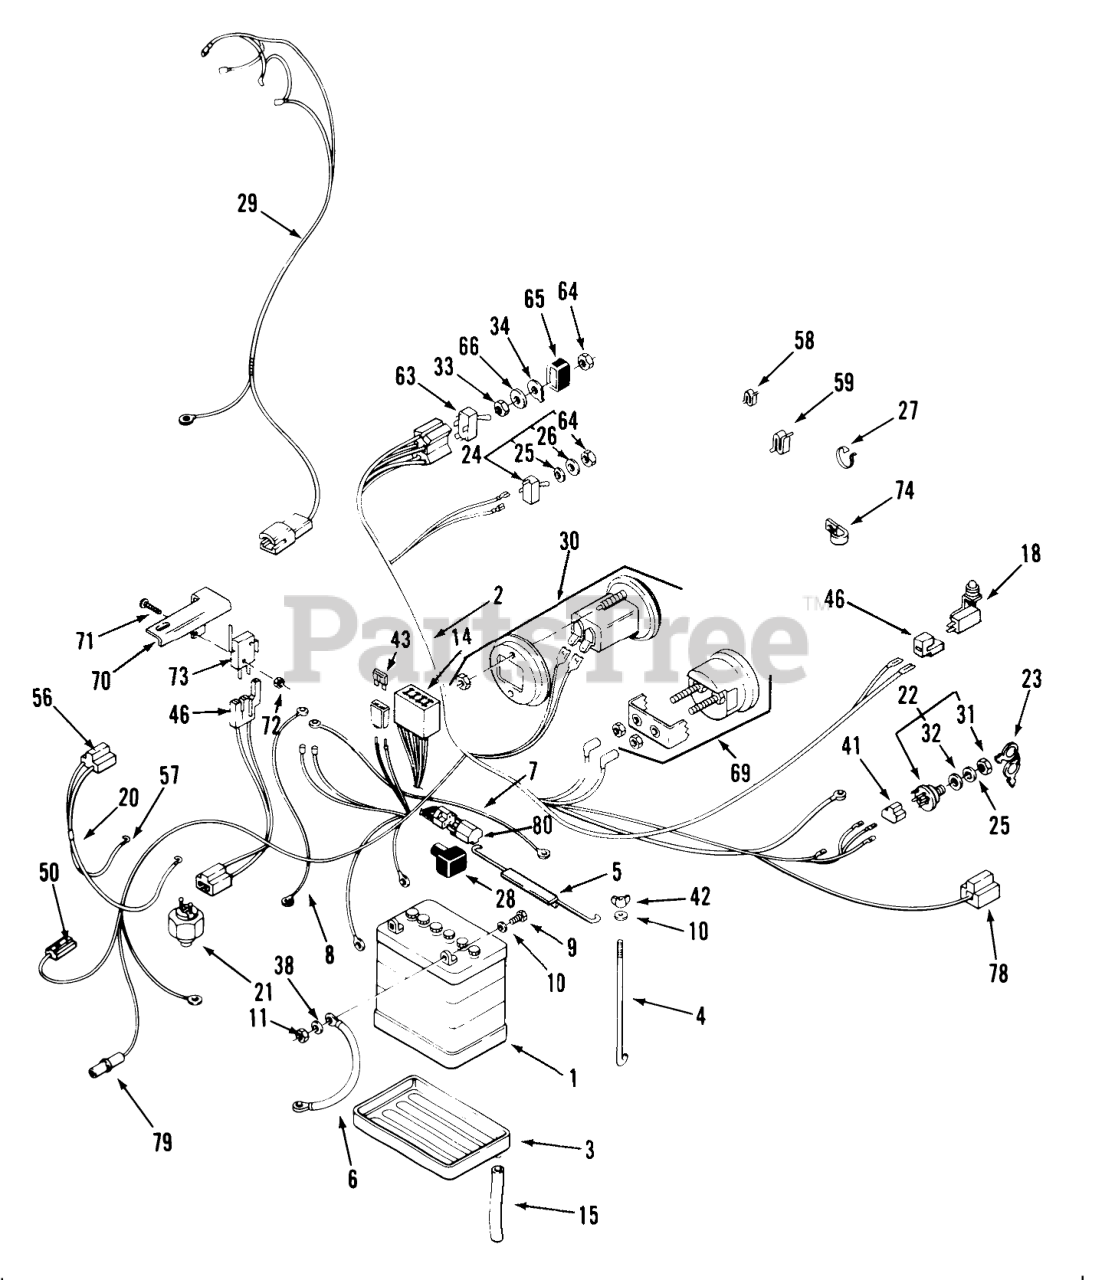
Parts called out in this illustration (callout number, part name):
1	Battery
2	MAIN-HARNESS & DIA
3	TRAY-BATTERY
5	ROD-BATTERY HOLD DWN
6	WIRE -BLACK
7	WIRE - 14" BLACK
8	ASS'Y-WIRE
9	Bolt
11	Nut
14	FUSE-HOLDER 4 WAY
15	TUBE-BATTERY DRAIN
18	Seat Switch
20	ASSY WIRING HARNESS
21	SWITCH (N.C.-TRANS)
22	Ignition Switch (Includes items 31 & 32)
23	Ignition Key
24	Light Switch (Includes items 33 & 34)
25	Washer
26	Washer
27	PLASTIC TIE
28	Boot
29	HARNESS-HEADLIGHT
30	Hourmeter (Includes 114017 Bracket, 915962 Keps Nut 2] & 5924 E.S. Nut #10-24 2])
32	LOCKWASHER
33	NUT-HEX, SPECIAL
34	TAB-WASHER
41	CONNECTOR-5 WAY-SERV
42	Nut
43	FUSE-BLADE, 15 AMP
46	CONNECTOR BODY
50	CONNECTOR BODY ELECT
56	CONNECTOR BODY B
57	TERMINAL-TAB RCPT
58	CLIP
59	SPEED CLIP
63	Electric Clutch Switch (Includes items 33, 34 & 64)
65	COVER-PTO SWITCH
66	WASHER
69	Voltmeter (Includes 109650 Clamp & 5924 #10-32 Nut 2])
70	BRKT-TRANS NEUT S R
71	Screw
72	NUT HEX 4-40 ELAST
73	SWITCH
74	CLAMP
78	CONNECTOR 5 WAY
79	Connector-Socket
80	RELAY
